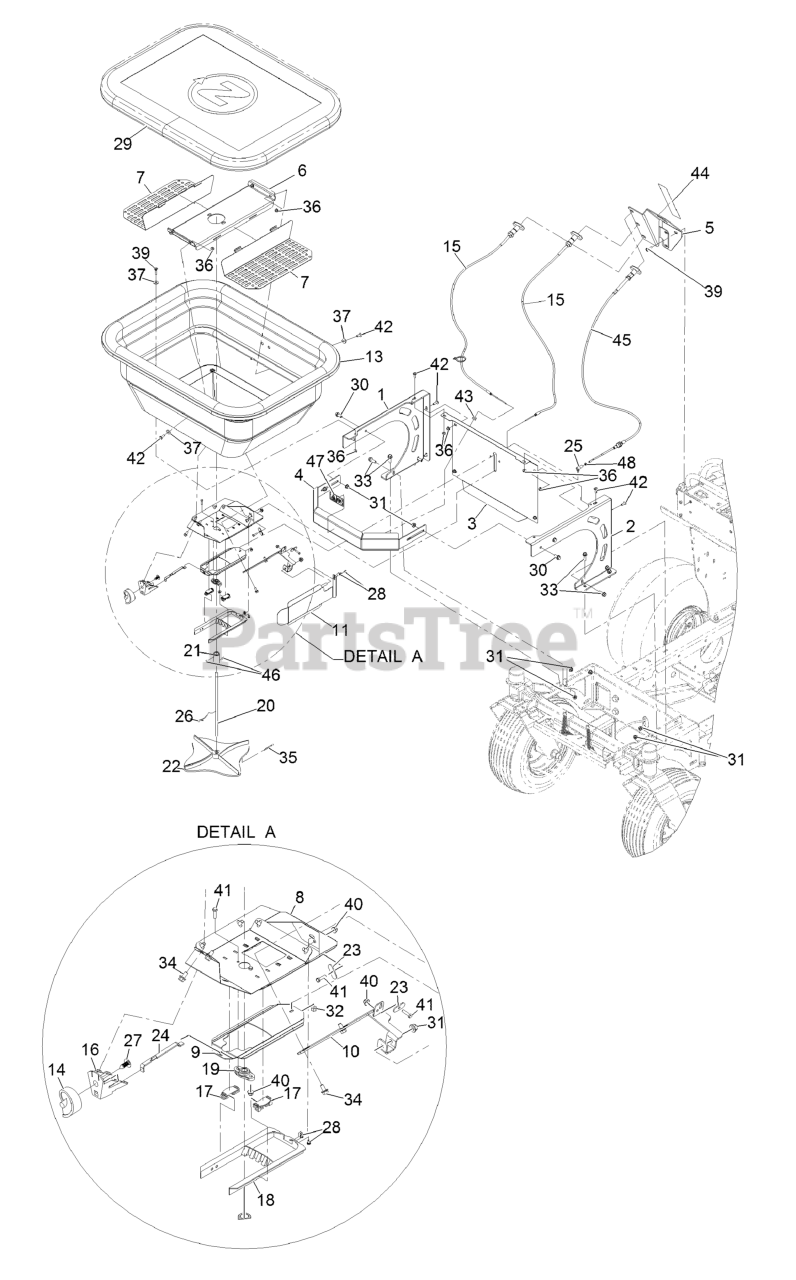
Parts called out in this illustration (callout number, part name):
1	Side-Hopper, Rt
2	Side-Hopper, Lt
3	Backshield-Hopper
4	BUMPER-FRONT, HOPPER
5	MOUNT-SPEEDOMETER
6	PAN-HOPPER, 220
7	SCREEN-HOPPER, 220
8	PLATE-BASE, HOPPER
9	Slide-Door, Hopper
10	Mount-Deflector, Side
11	Deflector-Side, Spreader
13	HOPPER-220LB
14	DIAL
15	CABLE-PUSH/PULL
16	MOUNT-DIAL
17	GUIDE-RATE, GATE
18	DIFFUSER
19	BEARING-FLANGE
20	SHAFT-HOPPER, 220
21	COUPLER-SS
22	SPINNER-SPREADER
23	RETAINER, CABLE
24	LINKAGE-GATE, RATE
25	BALL JOINT-SS
26	WIRE-AGITATOR
27	CLIP
28	RETAINER-CABLE, WIRE
29	COVER-HOPPER, LARGE
30	SCREW-HHF
31	Nut-Hex Flange
32	Nut,NYL Lock,#10-32,ST/ST 18-8
33	SCREW-HHF
34	SCREW-HHF
35	PIN-COTTER
36	Nut-Hex Flange
39	Screw-Hsbhf
40	Nut-Hex Flange
41	SCREW-HH
42	Screw-Hsbhf
43	Grommet-Rubber
44	Decal-Hopper Control
45	CABLE-PUSH/PULL
46	Screw-SQH
47	Decal-Dismemberment Hazard
48	Nut,Hex Jam Mch Scr,10-32,Sst
